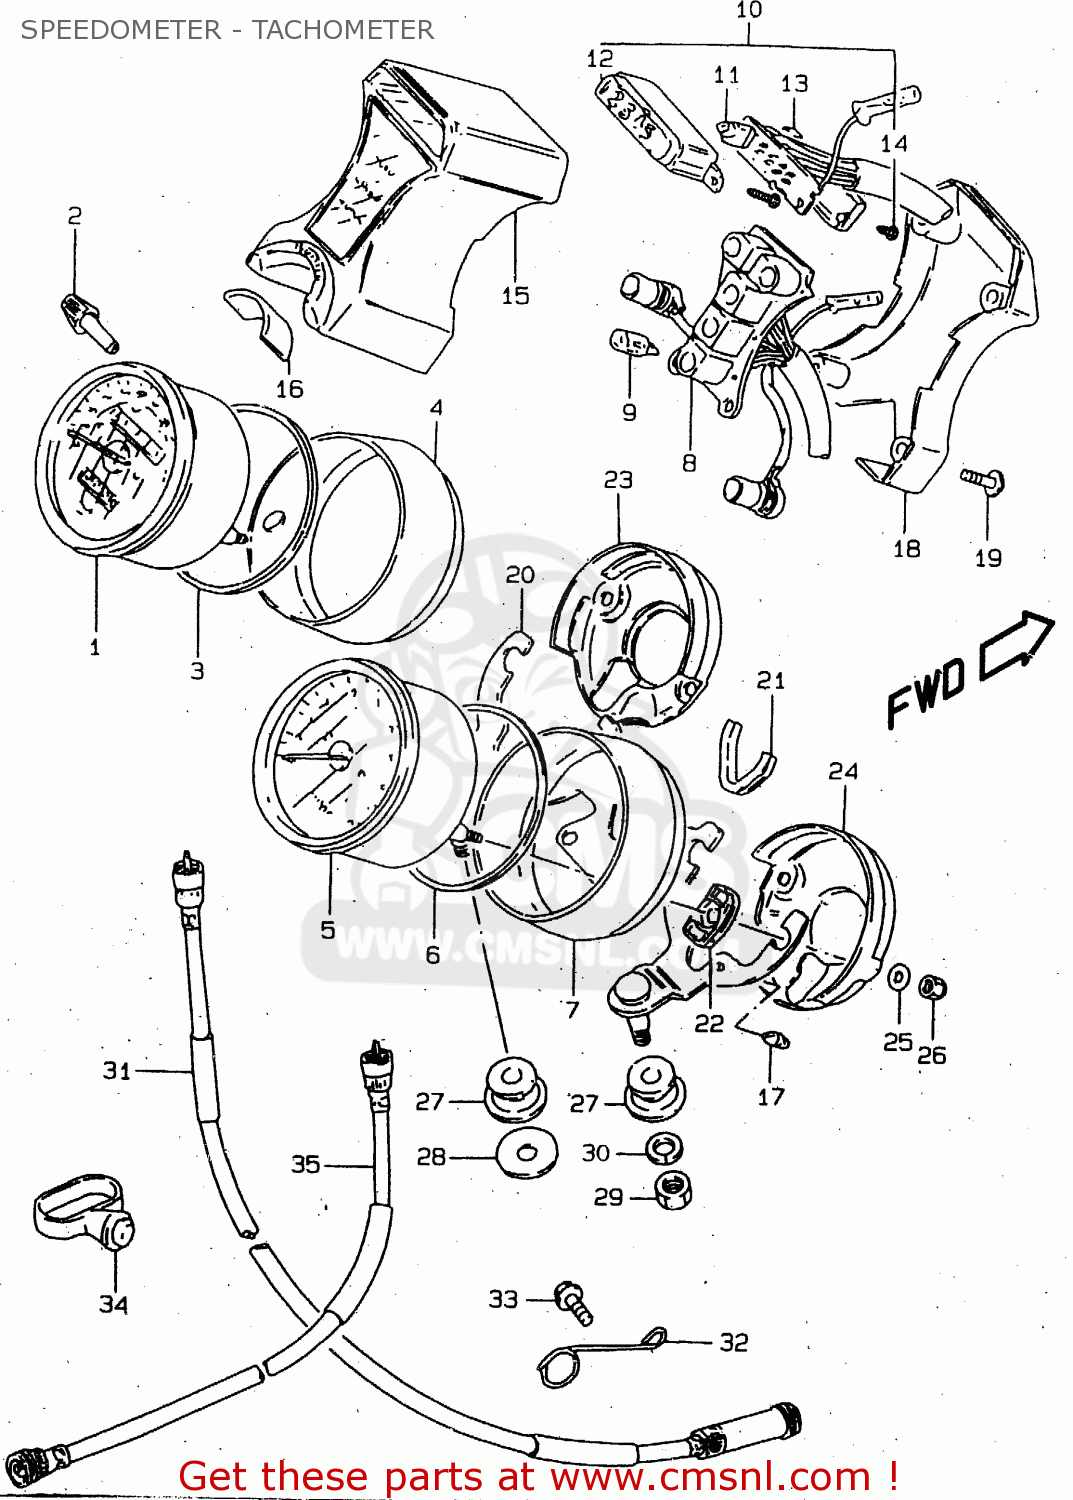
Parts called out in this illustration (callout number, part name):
1	SPEEDOMETER
2	KNOB
3	CUSHION
4	COVER,SPEEDOMETER
5	TACHOMETER ASSY
6	CUSHION
7	COVER,TACHOMETER
8	SOCKET
9	BULB(12V3.4W,T10)
10	INDICATOR ASSY,GEAR POSITION
11	BULB(14V1.12W)
12	CASE,GEAR INDICATOR
13	COVER,LWR
14	SCREW
15	BOX,PILOT
16	SEAL,IGNITION SWITCH
17	CUSHION
18	COVER,PILOT BOX LWR
19	SCREW
20	BRACKET
21	BRACKET,COVER
22	CUSHION,METER
23	ORNAMENT,SPEEDOMETER
24	COVER,TACHOMETER
25	WASHER
26	NUT
27	CUSHION,METER BRACKET
28	WASHER(8.5X28X1.6)
29	NUT
30	LOCK WASHER
31	CABLE ASSY,SPEEDOMETER
32	GUIDE,SPEEDOMETER CABLE
33	BOLT
34	GUIDE,CABLE
35	CABLE ASSY,TACHOMETER
